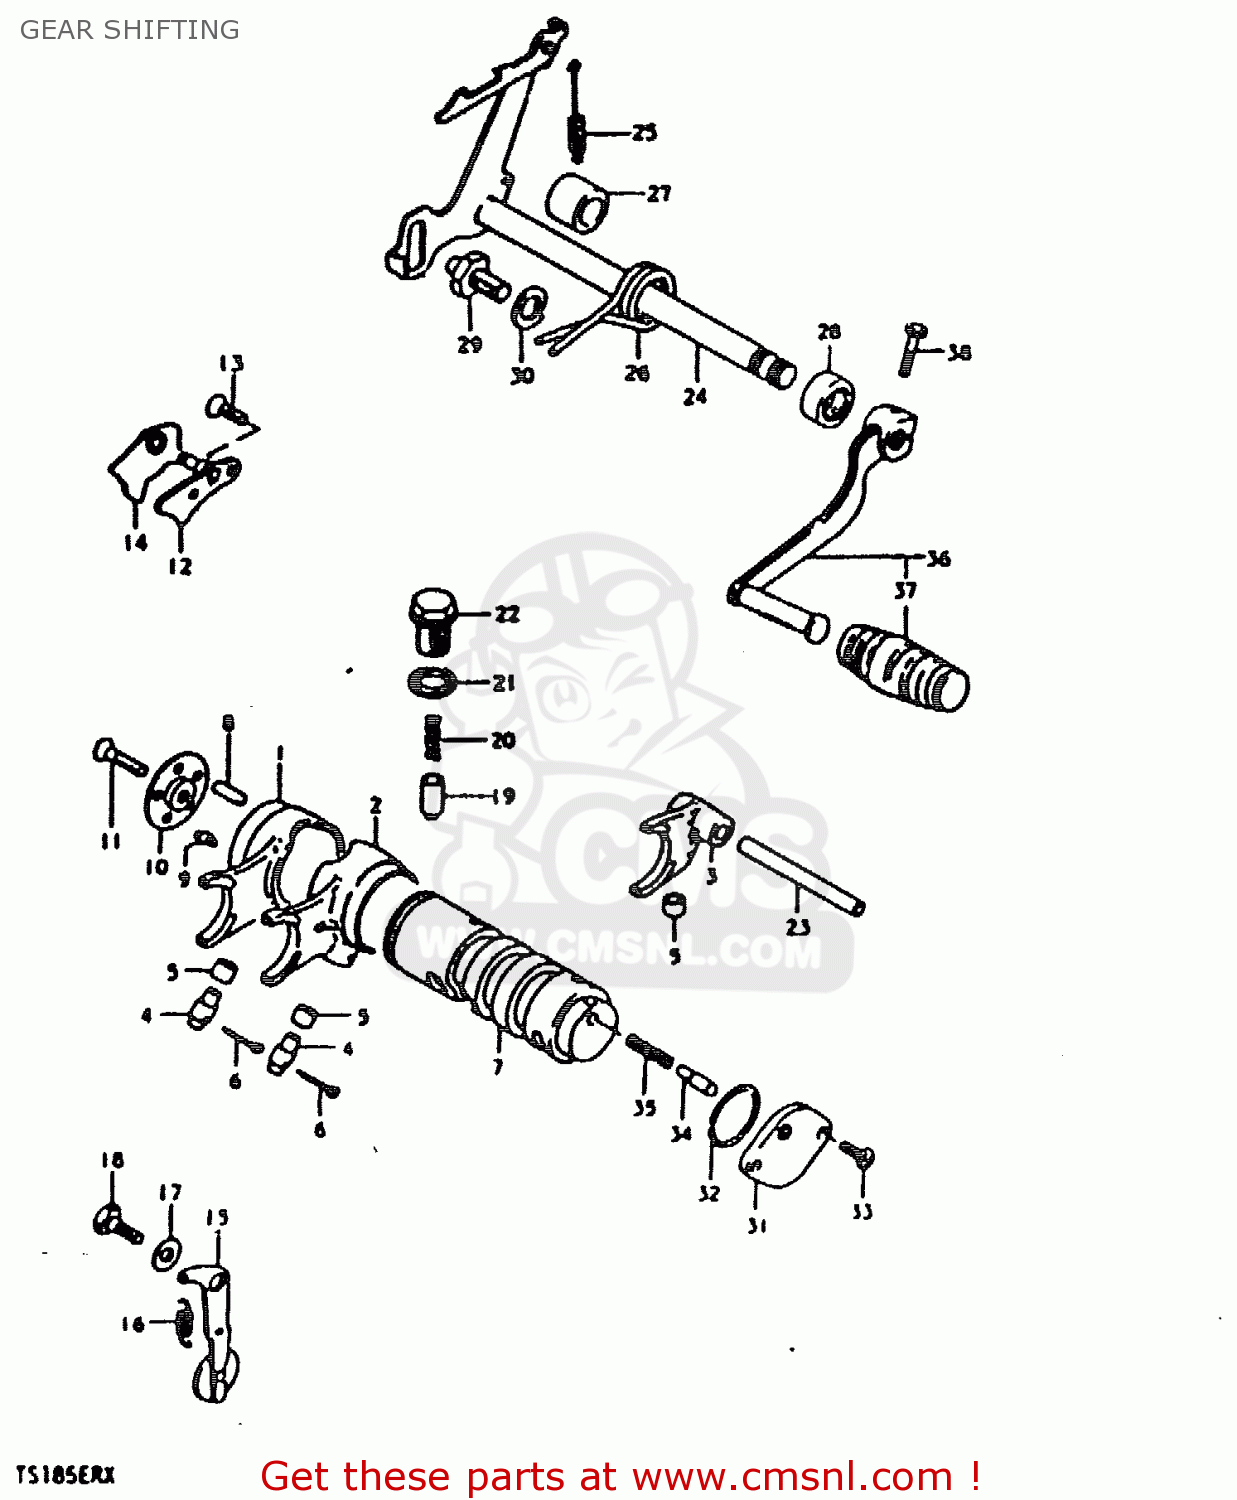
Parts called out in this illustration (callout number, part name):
1	FORK,GEAR SHIFT NO.1
2	FORK,GEAR SHIFT NO.2
3	FORK,GEAR SHIFT NO.3
4	PIN
5	SPACER(6X9.8X6)
6	PIN 25X20
7	CAM,GEAR SHIFT
8	ROLLER(4X13.8)
9	PIN
10	RETAINER,GEAR SHIFT CAM DR PIN
11	SCREW
12	GUIDE,GEAR SHIFT CAM
13	SCREW
14	PAWL,GEAR SHIFT CAM STOPPER
15	STOPPER,GEAR SHIFT CAM
16	SPRING
17	WASHER(6.5X16X2.3)
18	BOLT(6X16.1)
19	STOPPER,GEAR SHIFTING
20	SPRING
21	GASKET(14X19.2X2) (NAS)
22	BOLT,GEAR SHAFT CAM STOPPER
23	SHAFT,GEAR SHIFT FORK
24	SHAFT,GEAR SHIFT
25	SPRING
26	SPRING
27	SPACER(12X20X15.3)
28	OIL SEAL
29	STOPPER,GEAR SHIFT ARM
30	WASHER
31	BODY,GEAR SHIFT SWITCH
32	O-RING (D:2.4 ID:26.2)
33	SCREW
34	PIN(5X15.5)
35	SPRING
36	LEVER ASSY,GEAR SHIFT
37	RUBBER,GEAR SHIFT PEDAL
38	BOLT
